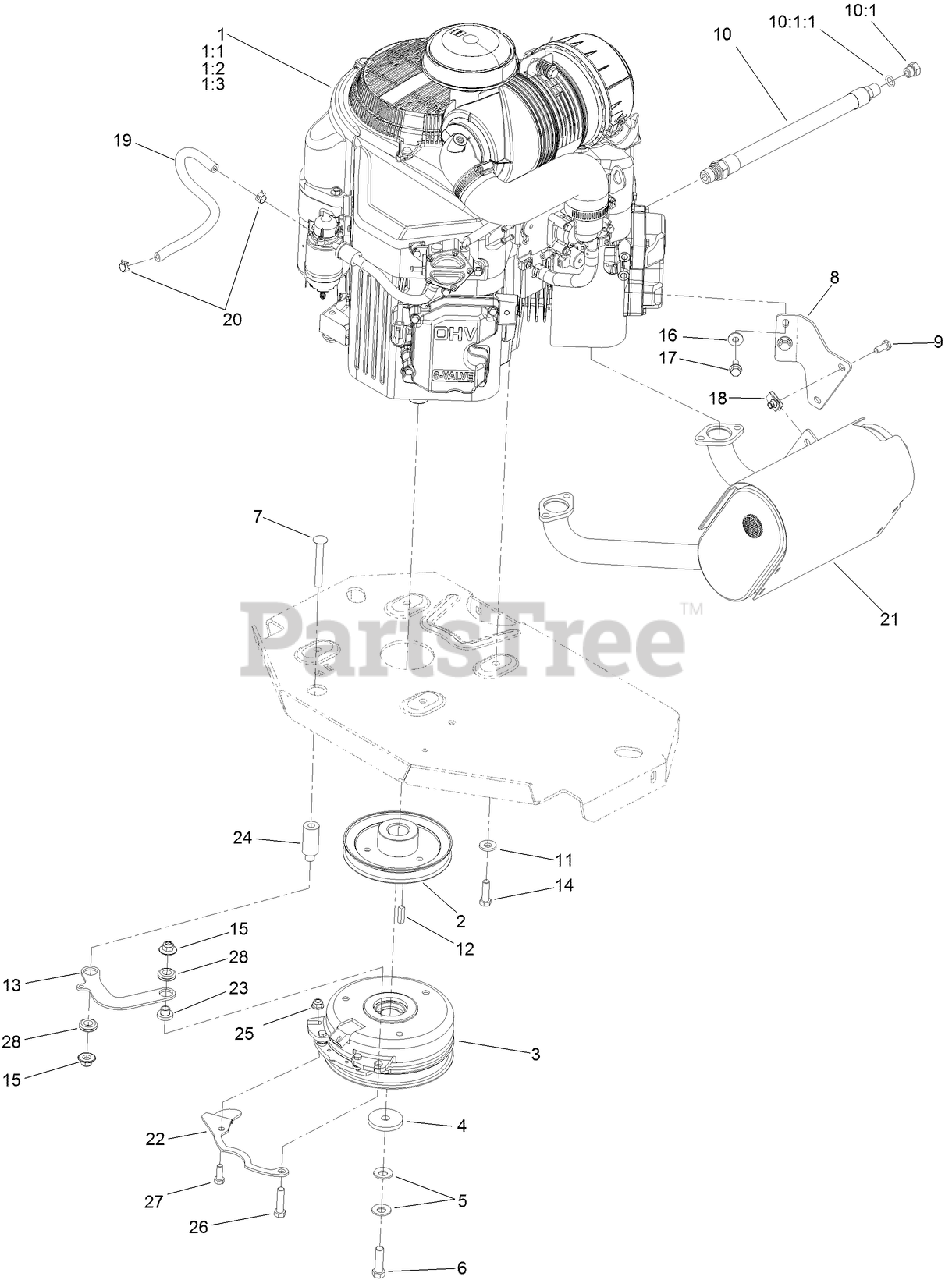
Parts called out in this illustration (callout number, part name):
1:1	KAWASAKI 49065-7007 ENGINE OIL FILTER
1:2	KAWASAKI 11013-7044 ENGINE AIR FILTER
1:3	KAWASAKI 11013-7045 SAFETY FILTER
2	SHEAVE
3	CLUTCH KIT
4	WASHER-CLUTCH
5	WASHER-SPRING
6	SCREW-HH
7	SCREW-CARR
8	BRACKET-MUFFLER
9	SCREW-HH
10	ENGINE OIL DRAIN HOSE ASM
10:1	PLUG-HH
10:1:1	O-RING
11	WASHER-BELLEVILLE
13	LINK-ANCHOR, CLUTCH
14	SCREW-HH
15	NUT-FLANGE, NI
16	WASHER-SPRING
17	SCREW-HHF
18	NUT-U
19	HOSE-FUEL
20	CLAMP-HOSE
21	MUFFLER
22	BELT-GUIDE
23	SPACER
24	SPACER
25	NUT-HF, NI
26	SCREW-HH
27	SCREW-HH
28	GROMMET-RUBBER
